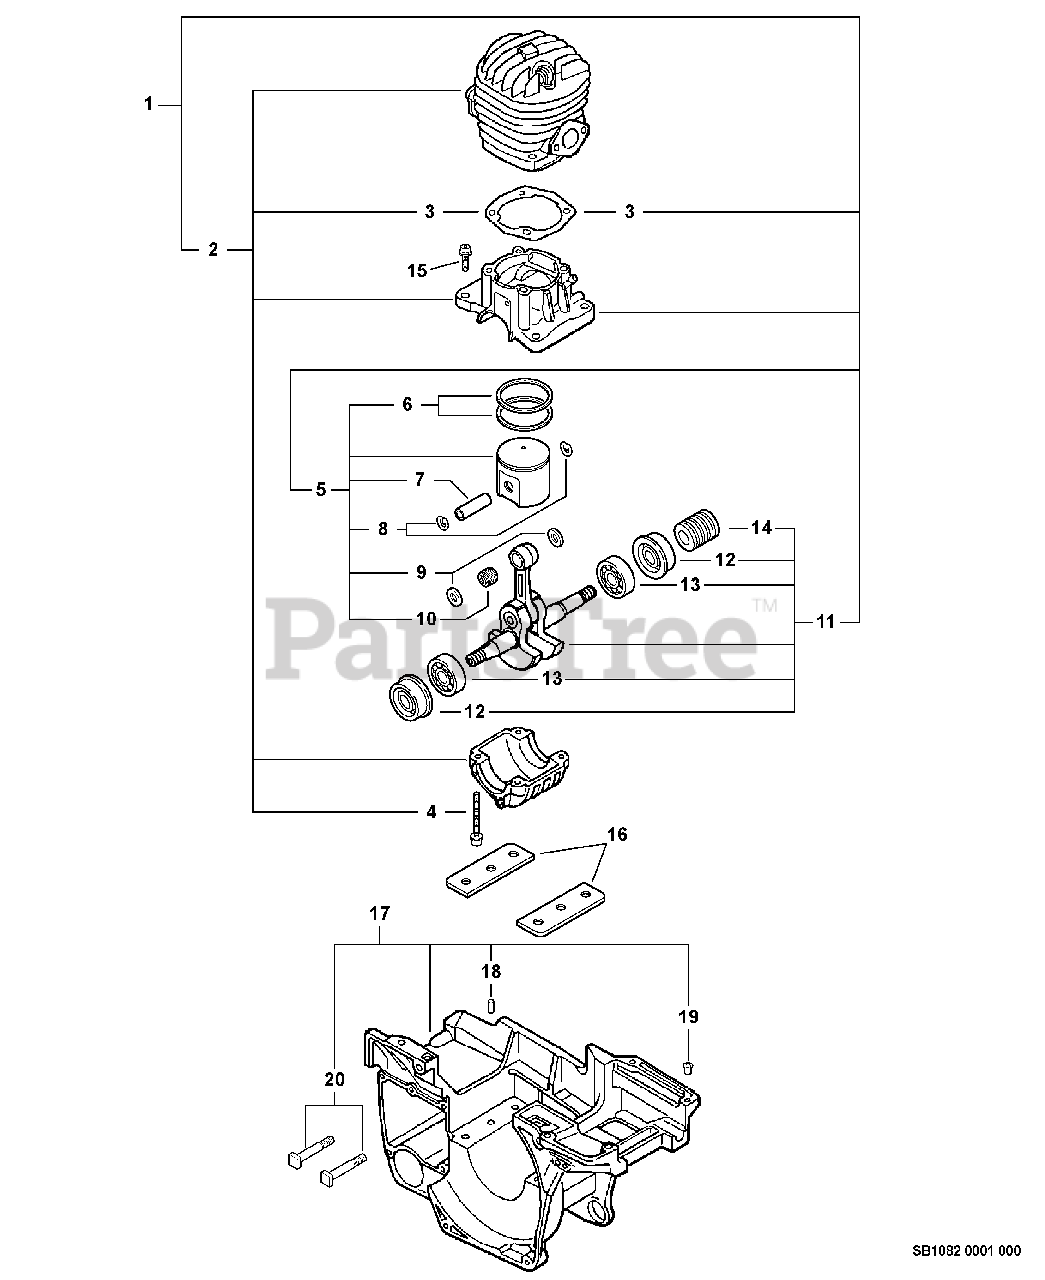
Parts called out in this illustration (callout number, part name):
1	SHORT BLOCK
2	CRANKCASE KIT
3	GASKET, CYLINDER
4	BOLT 5×55
5	PISTON KIT
6	RING, PISTON
7	PIN, PISTON
8	RING, SNAP
9	BEARING, NEEDLE 9
10	WASHER, THRUST
11	CRANKSHAFT ASSY
12	SEAL, OIL 12
13	BEARING, BALL - 6201 C3
14	GEAR, WORM
15	BOLT 5×22
16	PLATE, EYE
17	COVER, ENGINE
18	PIN, LOCATING 4
19	COLLAR 5.5×6.65×5
20	STUD, GUIDE BAR 8
